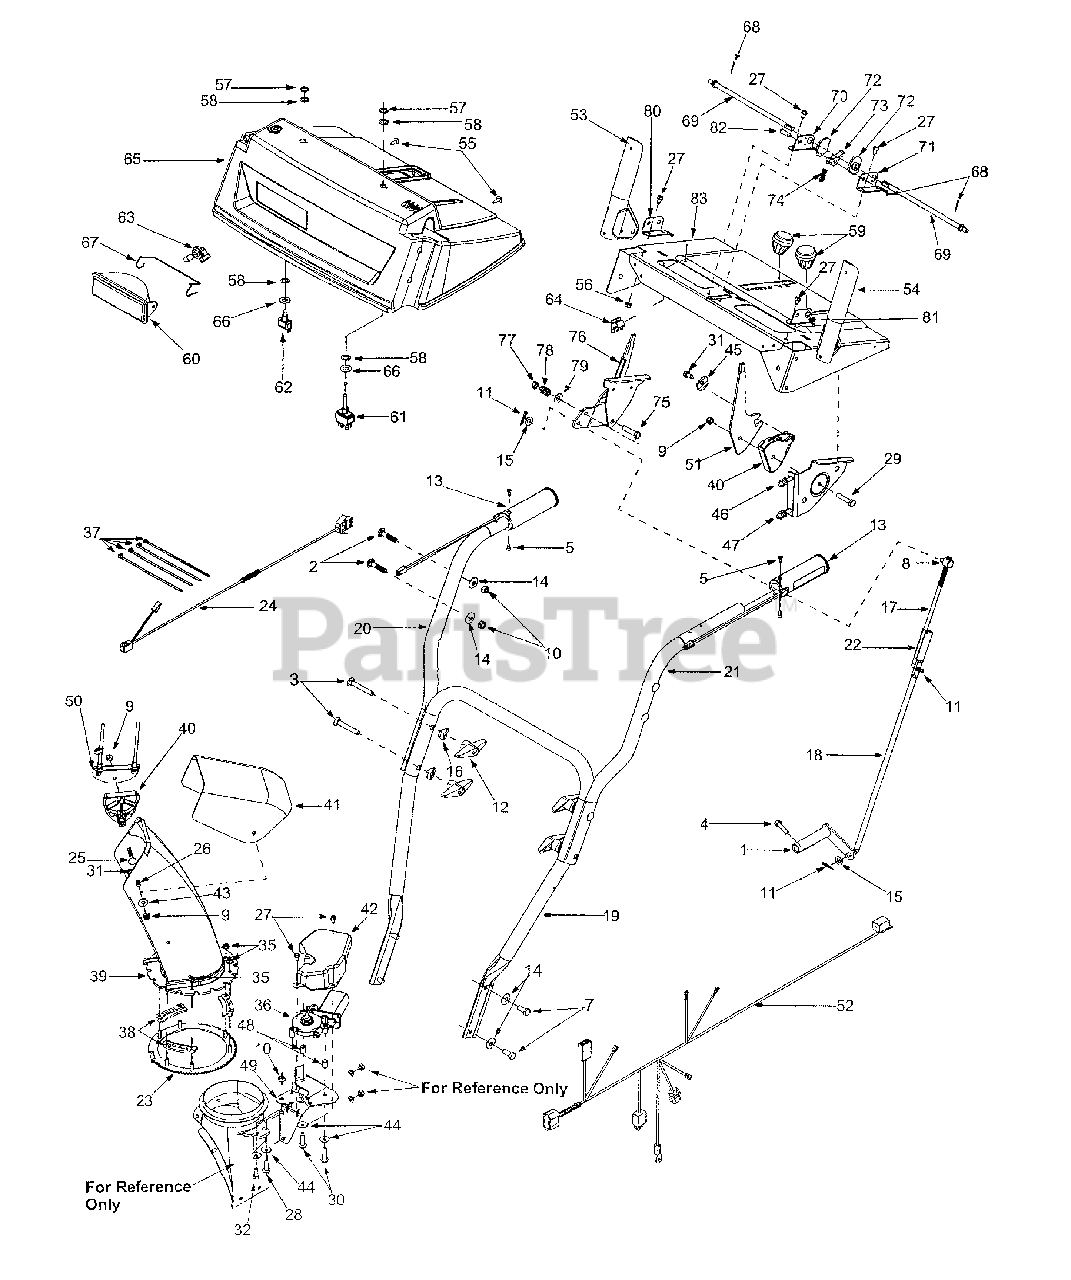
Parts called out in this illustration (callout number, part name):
3	Carriage Bolt 5/16-18 x 2.25"
4	TT Screw 1/4-20 x 1"
5	C-Sunk Screw #10-16x 0.625"
7	Hex Screw 5/16-18 x .75"
8	Ferrule
9	Hex Lock Nut 5/16-18
10	Hex Nut 5/16-18
11	Cotter Pin
12	Handle Knob
13	Heated Grip
14	Belleville Washer
15	Flat Washer
16	Saddle Washer
17	Shift Rod: Upper
18	Shift Rod: Lower
23	Gear Assembly: Ring
24	Electric Harness: Lower
25	Carriage Bolt: 5/16-18 x 1.5"
26	Carriage Bolt: 5.16-18 x .750"
27	TT Screw: 1/4-20 x 0.5"
28	TT Screw: 5/16-18 x 1"
29	Hex Screw: 5/16-18 x 1.5"
30	TT Screw: 5/16-18 x 1.25"
31	Hex Screw AB: 1/4-14 x 0.625"
32	Hex Screw: 5/16-18 x .75"
35	Hex Flange Lock Nut
36	Electric Motor: Chute Crank
37	Cable Tie
38	Chute Flange Keeper
39	Lower Chute
40	Cable Guide: Chute Tilt
41	Upper Chute
42	Motor Cover: Chute Rotation
43	5/16 Washer
44	Belleville Washer
45	Special Washer
46	Control Cable
47	Control Cable
52	Harness Assembly: Upper
53	Handle Assembly RH
54	Handle Assembly LH
55	Special Hex Screw
56	Hex Sems Nut: 1/4-20
58	Lock Ring: Toggle Switch
59	Shift Knob
60	Lamp Housing
61	Toggle Switch: Double Throw
62	Toggle Switch: Single Switch
63	Halogen Lamp: 50W, 12V
64	Mounting Clamp
65	Handle Panel
66	Flat Washer
67	Headlight Retainer
68	Cotter Pin: 3/32 x .75
73	Handle Lock Pawl
74	Compression Spring: .36 x 1.0
75	Hex Cap Screw: 3/8-24 x 1.5
78	Comp. Spring:.39 x .6 x .88
79	Bell Washer
82	Clevis Pin
